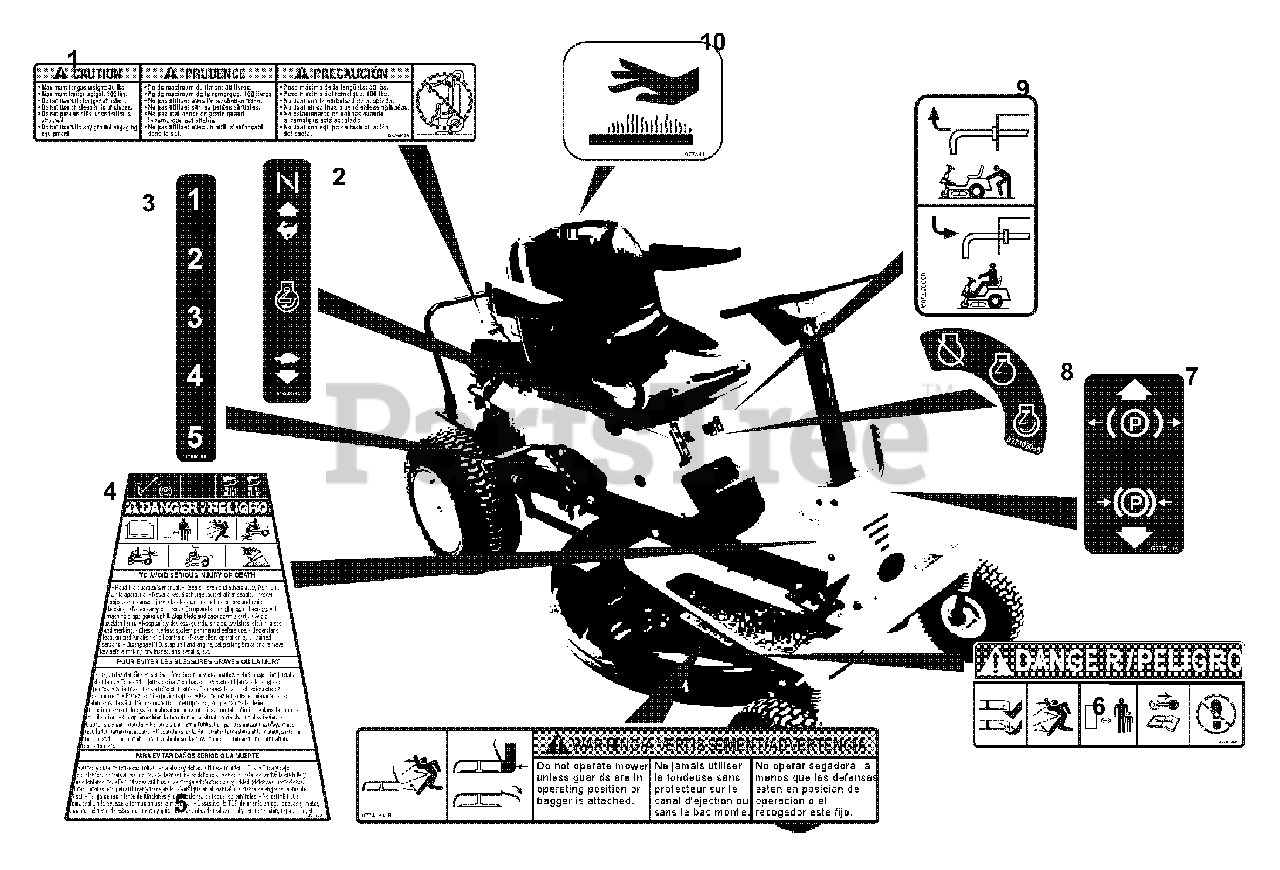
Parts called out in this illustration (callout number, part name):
1	DECAL-HITCH 100#
2	DECAL-THROTTLE RER/SPORT
3	DECAL, 5 POSITION CUT HEIGHT
4	DECAL-RER WARNING
5	DECAL, WARNING
6	DECAL, MOWER PAN DANGER
7	DECAL, PARKING BRAKE LEVER
8	DECAL - IGNITION
9	DECAL, TRANS DISCONNECT
10	DECAL, HOT SURFACE
